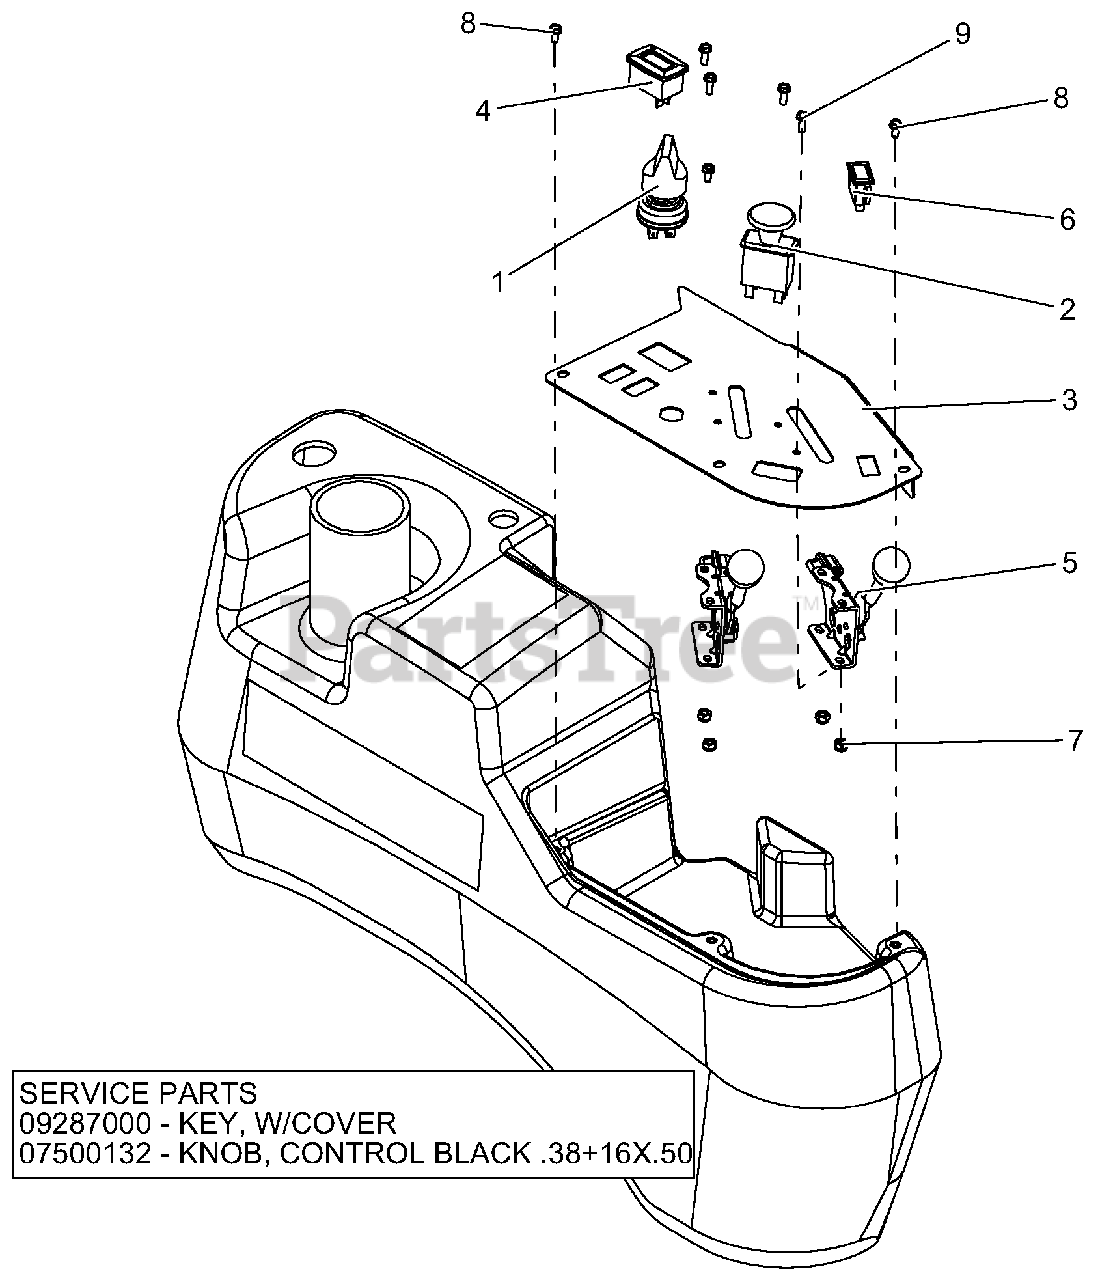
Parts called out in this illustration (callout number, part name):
1	SWITCH, IGNITION
2	SWITCH, CLUTCH
3	PANEL, CONTROL-BLACK
4	METER, HOUR W/MAINTENANCE
5	CABLE, PRO-CONTROL THROTTLE
5	CABLE, PRO-CONTROL CHOKE
6	LIGHT, INDICATOR
7	NUT-LK-NYL #10-24 YWZC
8	SCR-MCH 10-24X.38 HWHSTAINLESS
9	@SCR-MCH 10-24X.50 HWH YWZC
